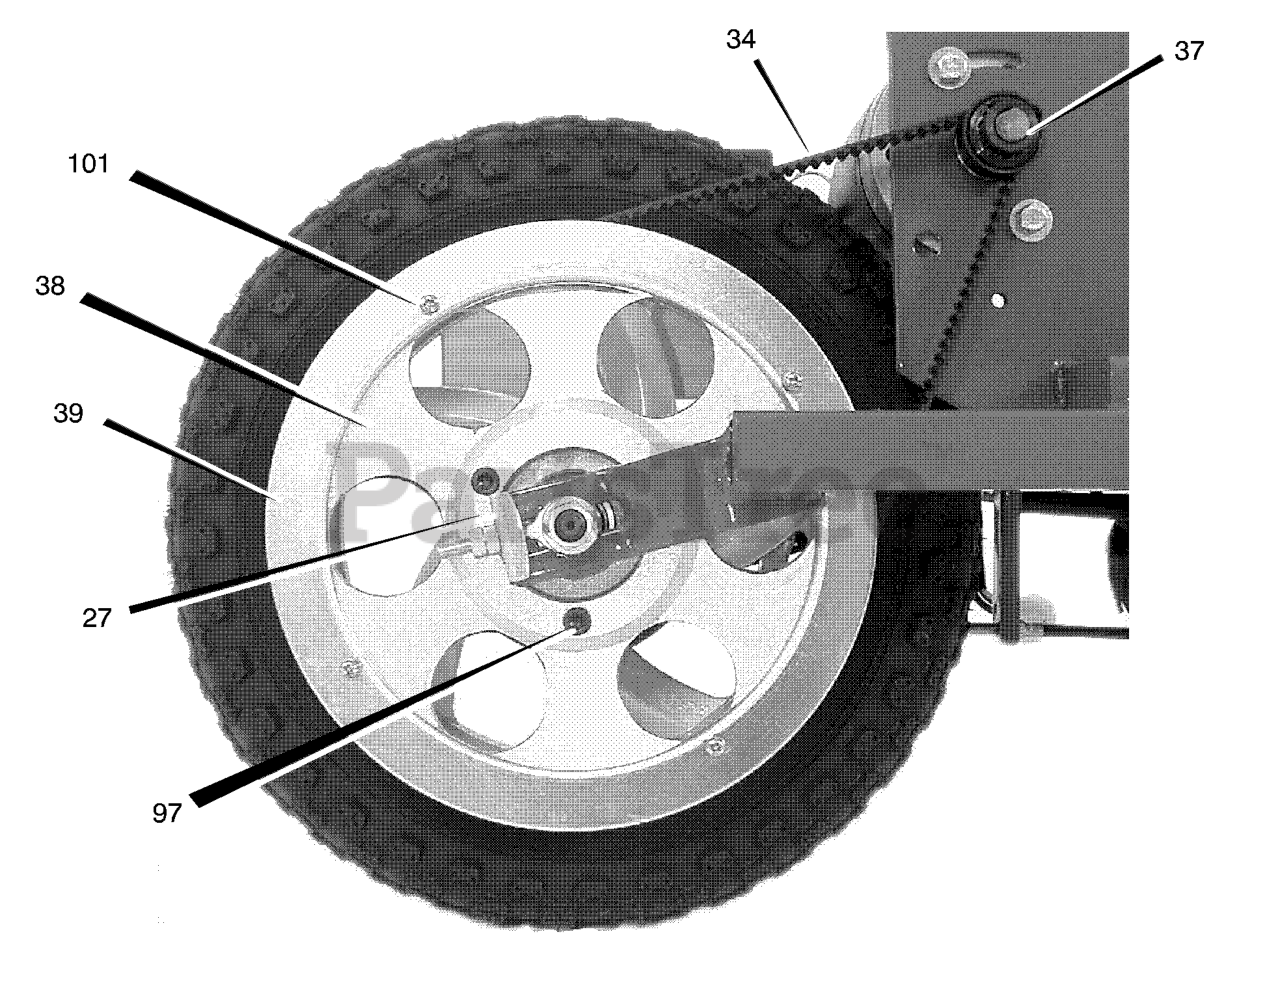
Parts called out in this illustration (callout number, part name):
27	Adjuster Ass'y., Rear Wheel
34	Belt, Drive
37	Gear, Motor
38	Gear, Wheel
39	Cover, Gear Wheel
97	Screw, Socket (3 required)
101	Screw (4 required)
